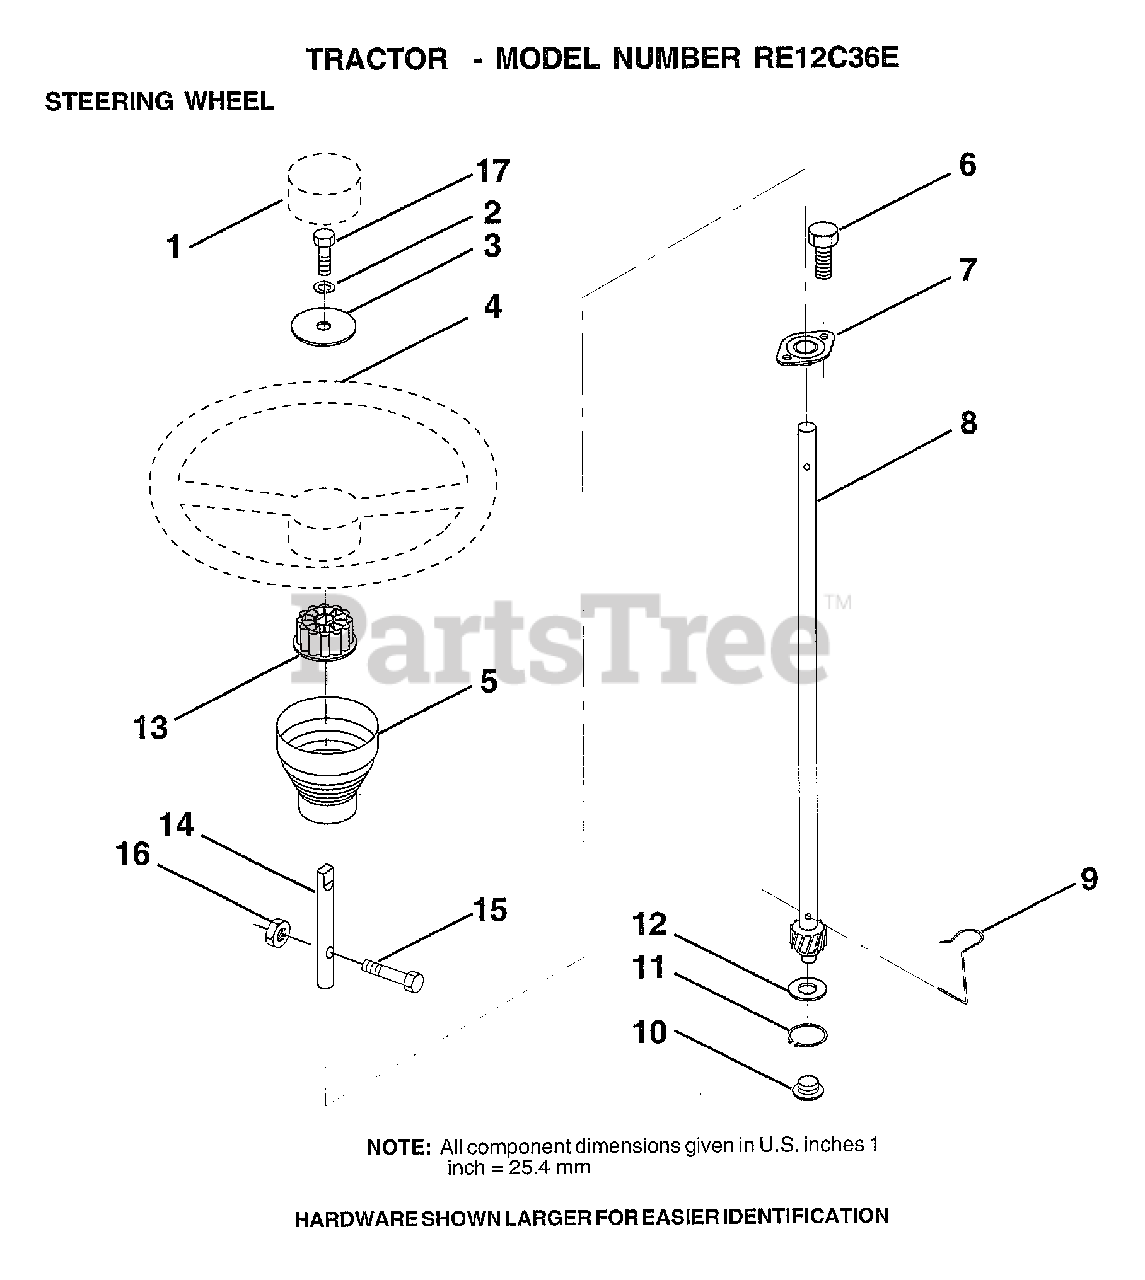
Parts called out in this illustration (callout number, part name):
1	ST WHL INSERT CAP
2	LOCKWASHER
3	WASHER
5	SLEEVE STEERING
6	"SCREW-TT,10-32 FL"
7	BUSHING.STR.623
8	SHAFT.STEERING.LR
9	STEERING CLIP
10	BUSHING STEER LWR
11	RING
12	WASHER LT
13	ADAPTER LT
14	EXT SHAFT STEERIN
15	BOLT
16	NUT
17	BOLT
